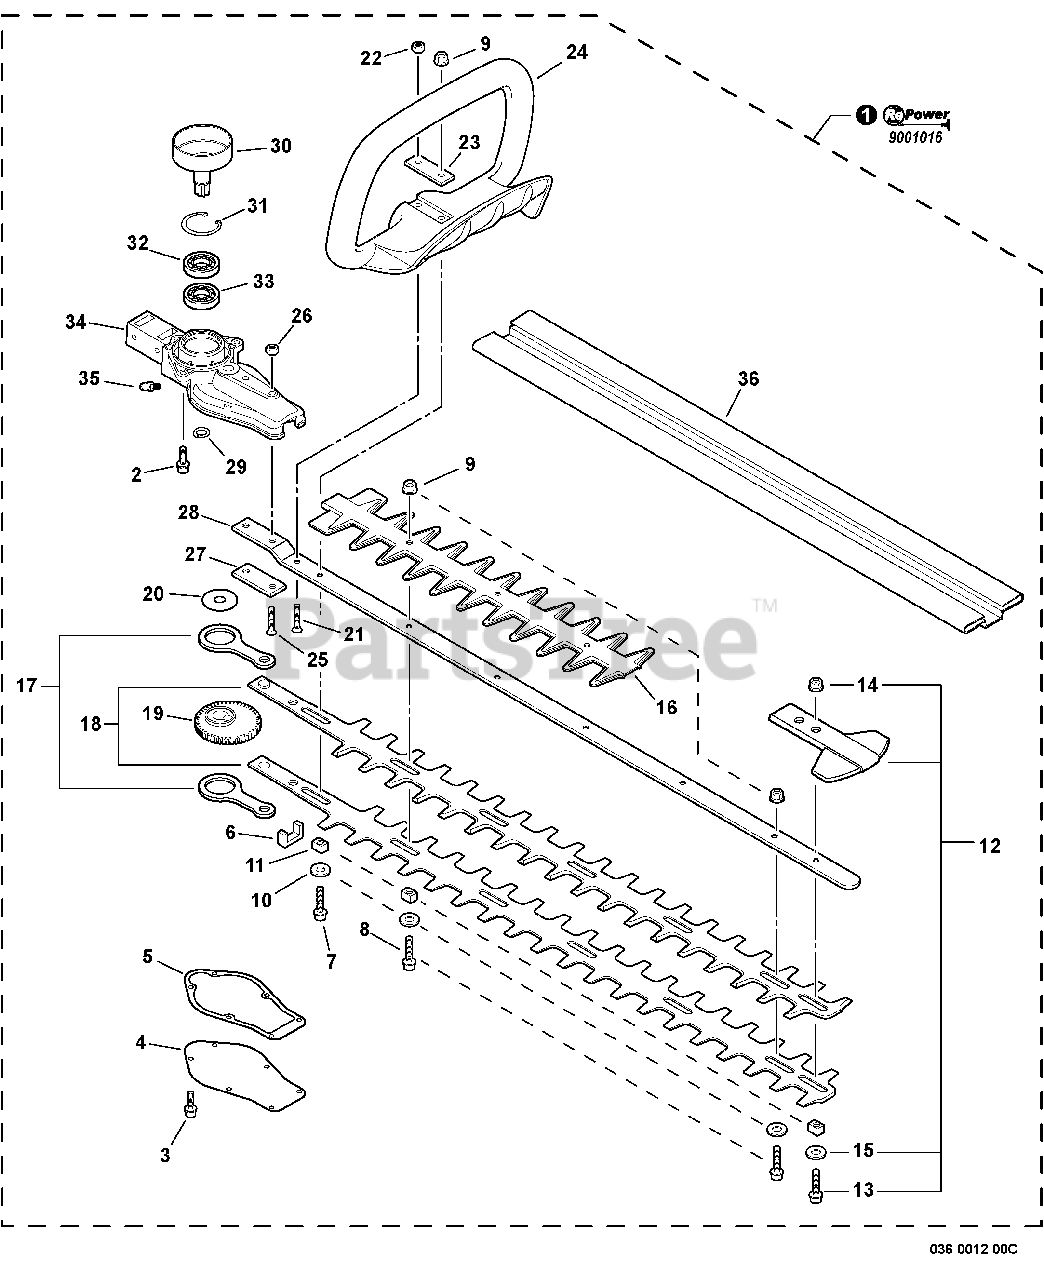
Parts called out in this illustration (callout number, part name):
1	CUTTING HEAD KIT
2	BOLT 5×20
3	BOLT 4×10
4	COVER, GEAR CASE
5	GASKET, GEAR CASE
7	BOLT 5×40
8	BOLT 5×20
9	NUT, FLANGE M5
10	GUIDE, BLADE 5
11	WASHER 5
12	TIP GUARD KIT
13	BOLT 5×20
14	NUT, FLANGE M5
15	WASHER 5
16	GUARD, CUTTER BLADE
17	CONROD
18	CUTTER 24"
21	SCREW 5×30
22	NUT, LOCK M5
23	PLATE, EYE
24	HANDLE, FRONT
25	SCREW 6×25
26	NUT, HEX M6
27	PLATE, EYE
28	SUPPORT, BLADE 24"
29	RING, SNAP 14
30	DRUM, CLUTCH
31	RING, SNAP 35
32	BEARING, BALL 6202
33	BEARING, BALL 6202
34	GEAR CASE ASSY
35	FITTING, GREASE
36	SCABBARD 26.5"
